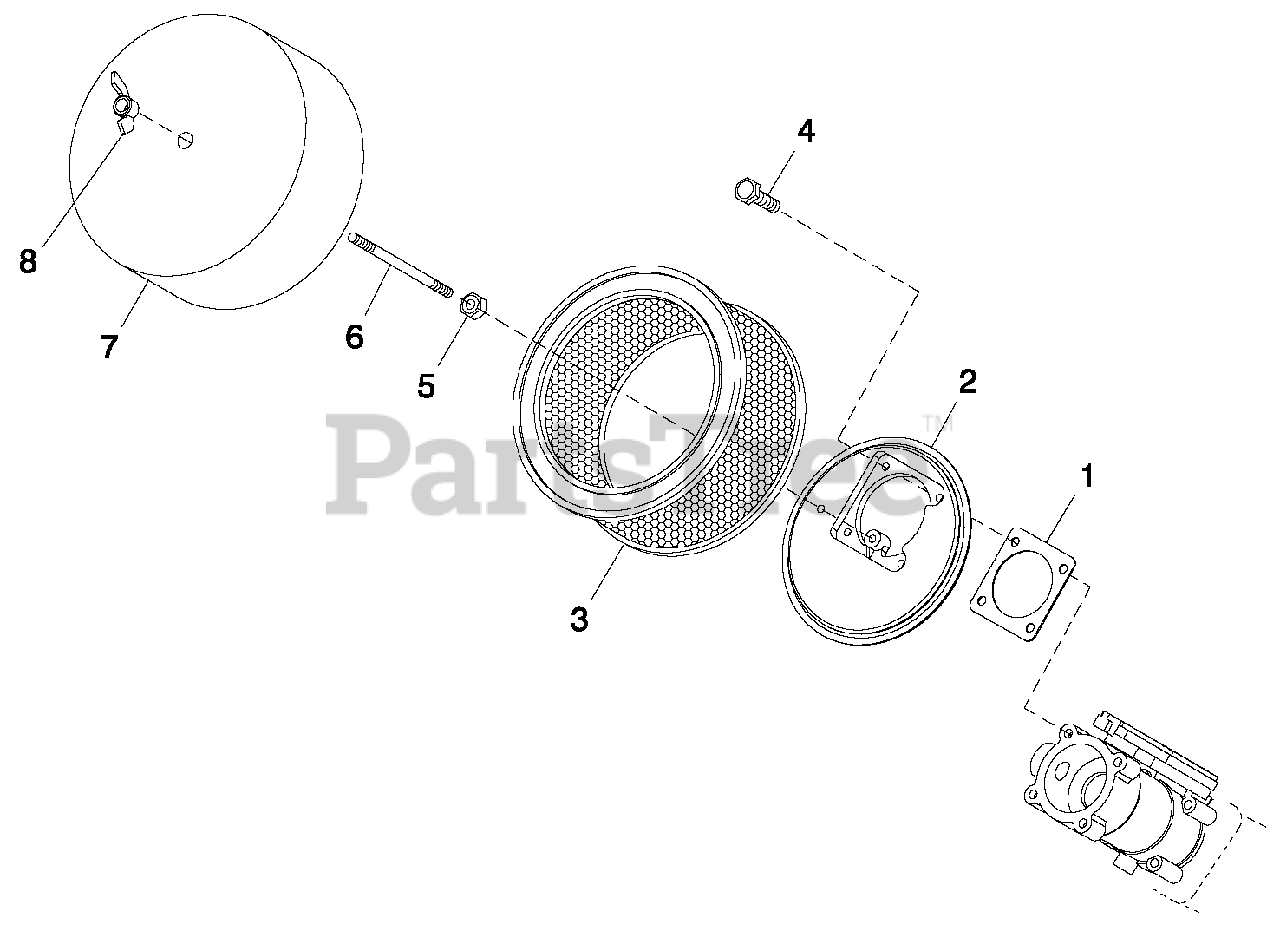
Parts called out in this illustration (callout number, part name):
1	ROTOR-2390-45KD1 CPL
2	ROTOR-2390-35KD1 CPL
3	ROTOR-2390-45KD1 CPL (G2)
4	ROTOR-2390-35KD1 CPL (G2)
5	ROTOR 25KW 3PH DIRECT 390 1800
6	ROTOR 25KW 1PH DIRECT 390 1800
7	PLATE, AIR CLEANER TOP 2.4L
8	NUT WING 1/4-20 NYLK
